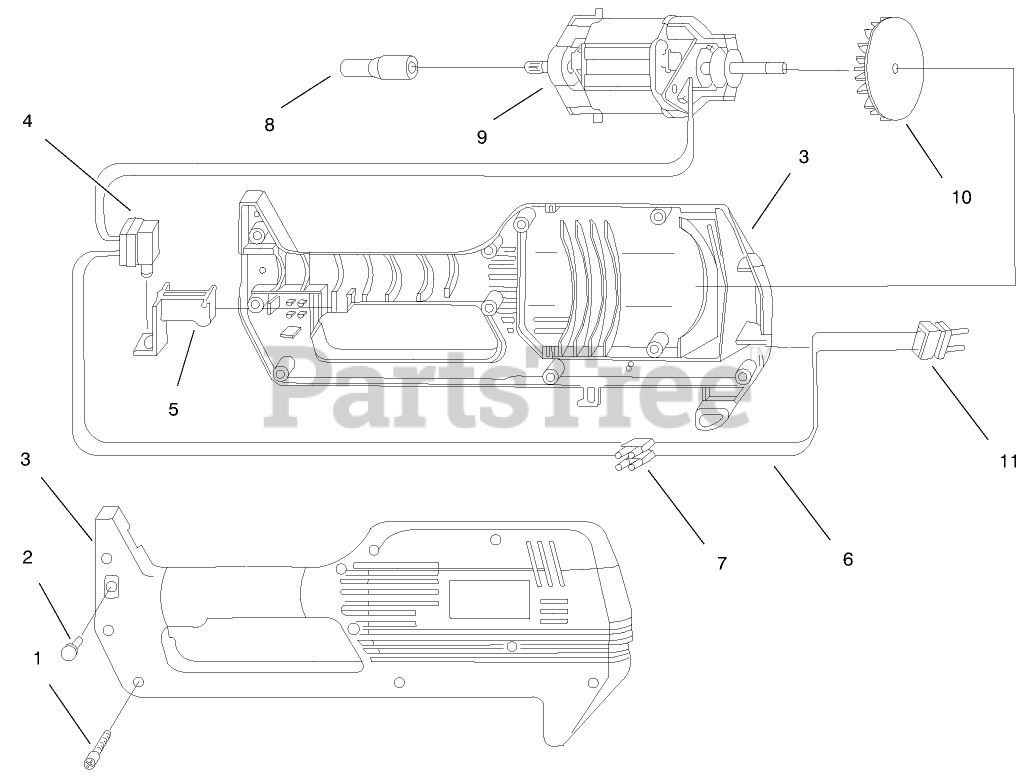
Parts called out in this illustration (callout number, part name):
1	SCREW - HOUSING
2	ANTI-ROTATION SCREW
3	HOUSING - MOTOR
4	SWITCH
5	PLUGS
6	LEAD - WIRE
7	BLOCK - TERMINAL
8	DRIVER
9	Motor (Incl. Ref. #8-10)
10	FAN - COOLING
11	HARNESS
